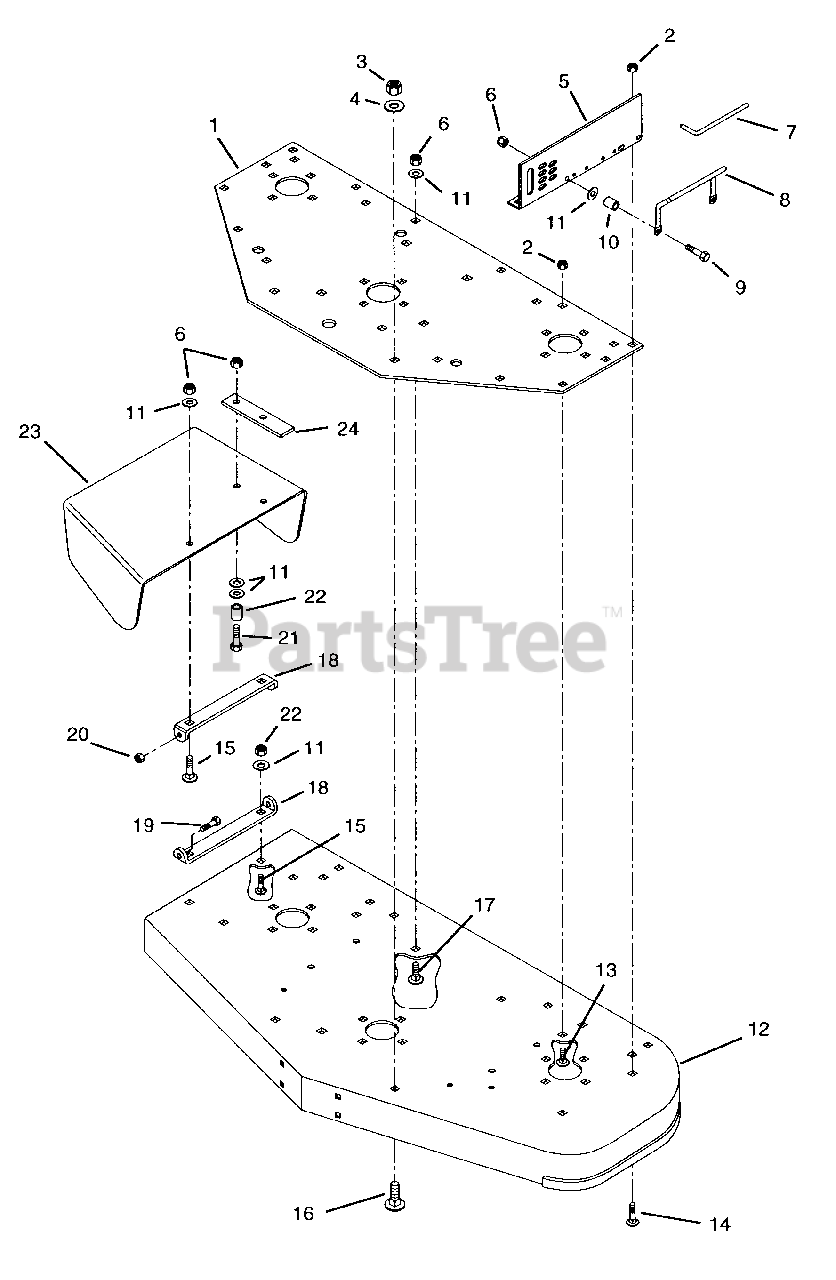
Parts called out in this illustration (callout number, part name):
1	Pnlate, Support
2	Nut-Locking-Nylon .312-18 w/Insr Grade 2
3	Nut-Locking-Nylon .50-13 Grade 5
4	Washer-Flat-Steel .531 x 1.250 x .100
5	Bracket, Mower Side Support Left Hand
6	Nut-Locking-Nylon .375-16 w/Insr Grade 2
7	Pin, Mower Locking
8	Handle
9	Bolt-Hex .28-16 x 1.75 Grade 5
10	Bushing
11	Washer-Flat-Steel .406 x.812 .065
12	Weldment, 50" Mower Fabricated
13	Bolt-Round Head Square Neck .31-18 x .62
14	Bolt-Round Head Square Neck .31-18 x 1.0
15	Bolt-Round Head Square Neck .38-16 x 1.0
16	Bolt-Round Head Square Neck .50-13 x 1.00
17	Bolt-Round Head Square Neck .375-16 x .75 Grade 1
18	Bracket, Chute
19	Bolt-Hex .25-20 x .875
20	Nut-Locking-Nylon .250-20 w/Insr Grade 2
21	Bolt-Hex .38-16 x 1.50 Grade 5
22	Bushing-Sleeve .407 x .812 x .065
23	Shield, Safety Extension 50" Mower
24	Limiter, Discharge Chute, 50"
